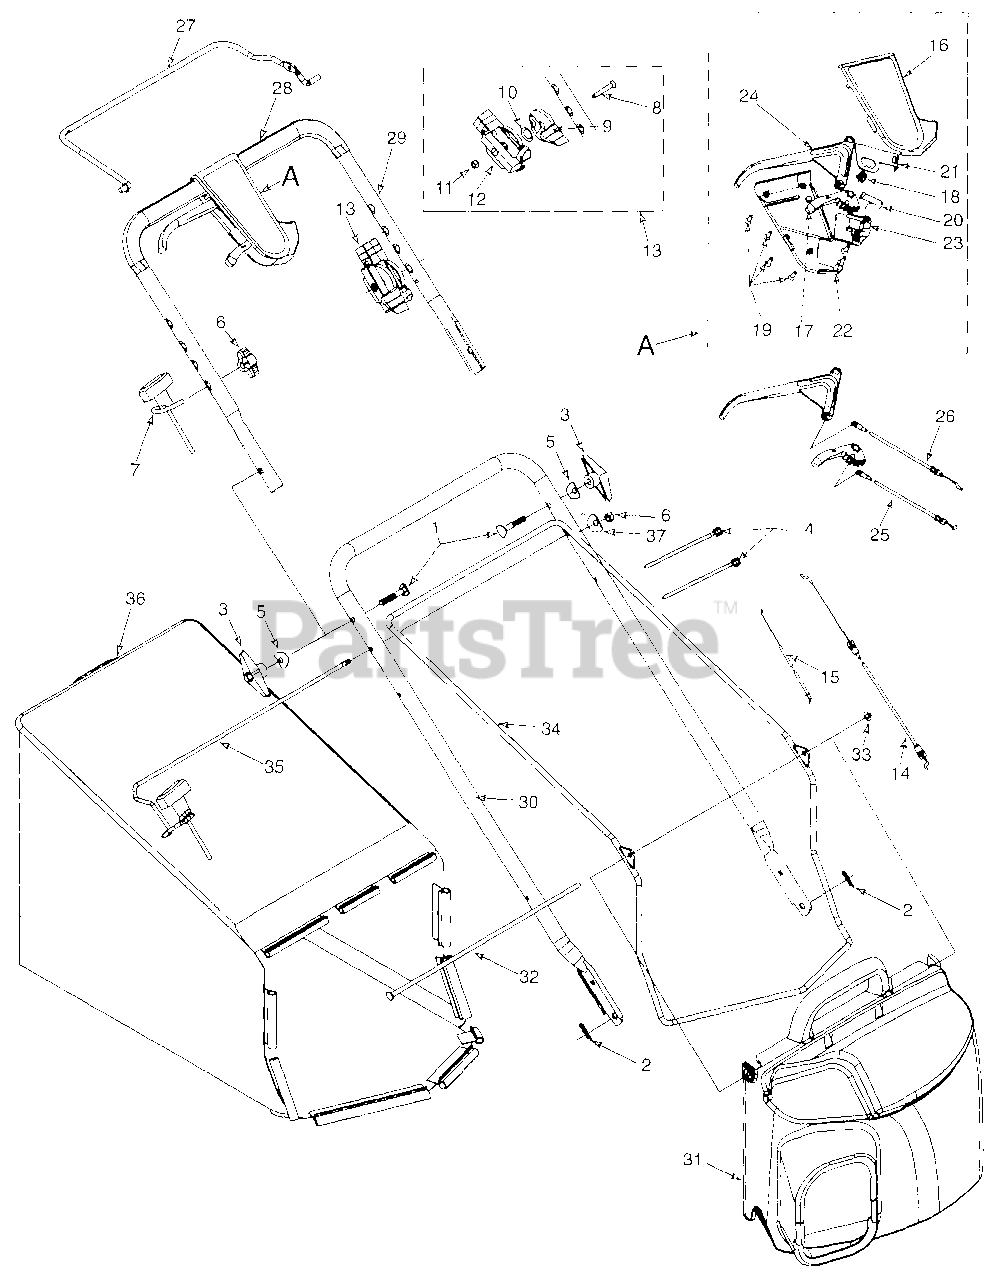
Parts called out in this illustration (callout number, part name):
1	Bolt Cur. Carr. 5/16-18 x 2.0
2	Cotter Pin .072 x t.12 Lg.
3	Knob Ass'y 5/16-18
4	Strap 4.3 Lg.
5	Wash. Sad. .320 ID x .830 OD
6	Hex Nut 5/16
7	Rope Guide Eyebolt
8	Screw 1/4-20 x 1.81
9	Throttle Lever
10	Spring Wash. Curved
11	Nut 1/4-20 Top locknut Insert
12	Housing, Throttle
13	Throttle Control
14	Control Cable 47" Lg.
15	Cable Throttle 60" Lg.
16	Upper Control Housing
17	6 Speed Shift Lever
18	Gear Insert
19	C Sunk Tap Screw #10 x .75
20	Shift Lever Spring
21	6 Spd. Rack Cable Brkt.
22	Lower Control Housing
23	Cable Mounting Cap
24	Control Lever
25	6 Spd. Cable
26	S.P. Cable
28	Foam Grip (2 Reqd.)
31	Grassbag Cover w/Label
32	Pivot Rod
33	Cap Nut
36	Grassbag
37	Saddle Washer
